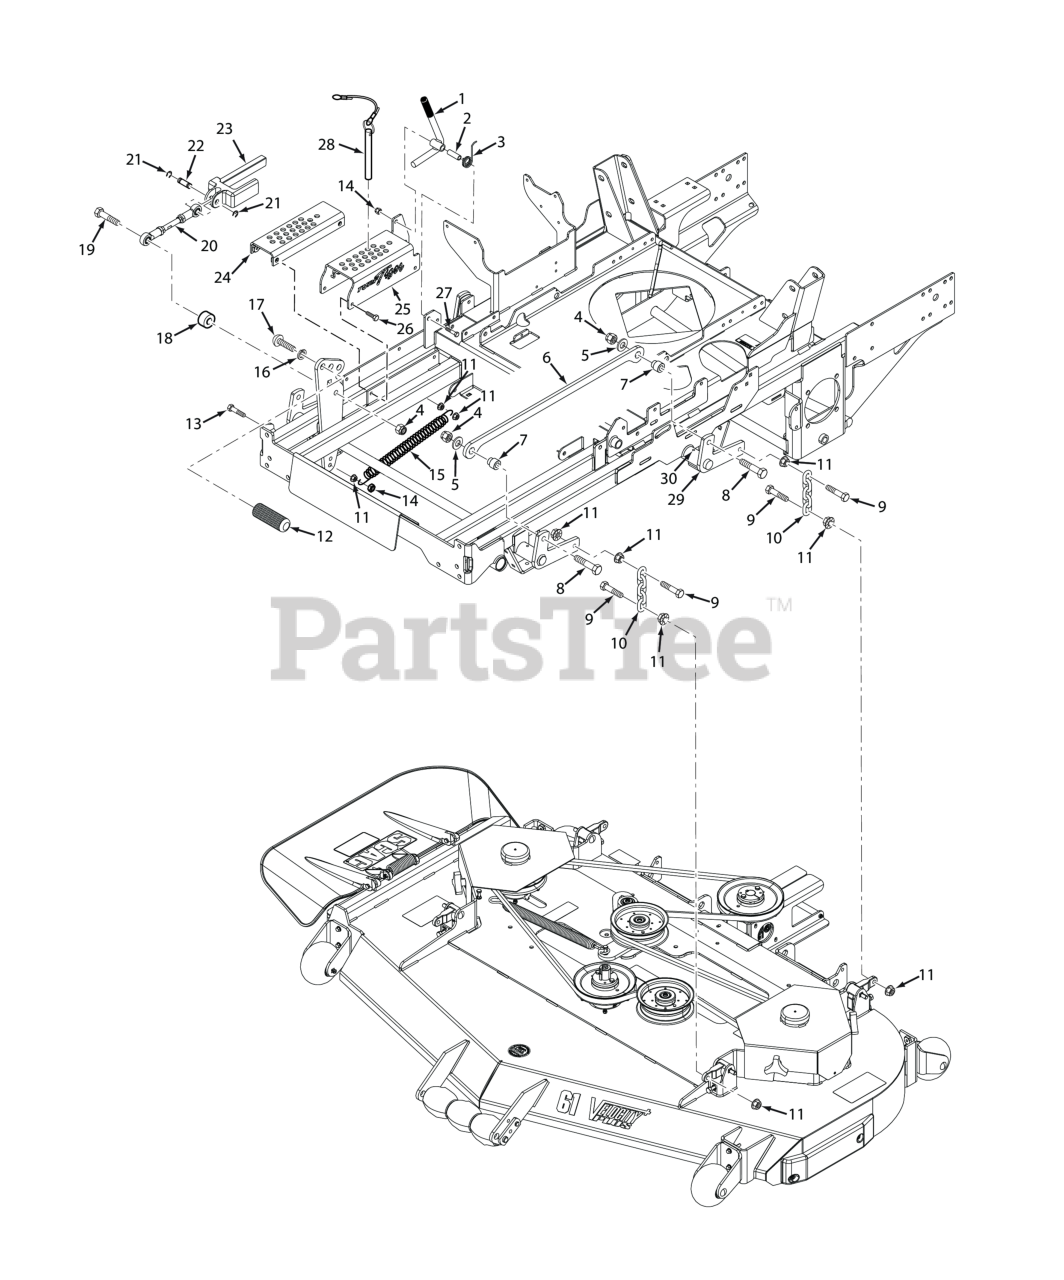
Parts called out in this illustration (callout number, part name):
1	Deck Latch Weldment w/Grip
2	Bushing, .502 O.D.
3	Spring, Torsion - Lever Return
4	HEX LOCKNUT, ELASTIC STOP, 1/2-13
5	Flat Washer, 1/2 (.562 x 1.375 x .109)
6	Pivot, Deck Link
7	Pivot, Deck Link
8	Bolt, Hex Head 1/2-13 x 2-1/4"
9	Bolt, Hex Head 3/8-16 x 1-1/2" B&S 32BV
10	Footplate
11	NUT, 3/8-16 SERRATED FLANGE HEX HEAD
12	Foot Pedal, Height Adjustment
13	Bolt, Hex Head 3/8-16 x 1-1/2" Grade 8 Black
14	Bolt, Hex Head 3/8-16 x 1" Ser. Flg.
15	Spring, Ext. Deck Lift
16	Lockwasher, 5/8" Spring
17	Capscrew, 5/8-11 x 1-1/2"
18	Spacer, Radiator
19	Hex Head Bolt, 1/2-13 x 2"
20	Linkage Assembly, Deck Lift
21	Retaining Ring, 1/2" Ext. "E"
22	Pin, Deck Lift
23	Slide, Height Adjust (INCL. 10,11,12)
24	Weldment, Lower Cutting Height
25	Adjustment Bracket, Cutting Height Upper
26	Bolt, Hex Wshr Head 5/16-18 x 1-1/4"
27	Bolt, Hex Head 3/8-16 x 2-1/4" - 61"
28	Lanyard, Deck Height Pin Assembly
29	LIFT BELLCRANK WLMT, LH REAR
30	GREASE FITTING, STR. 1/4-28 SELF TAP.
